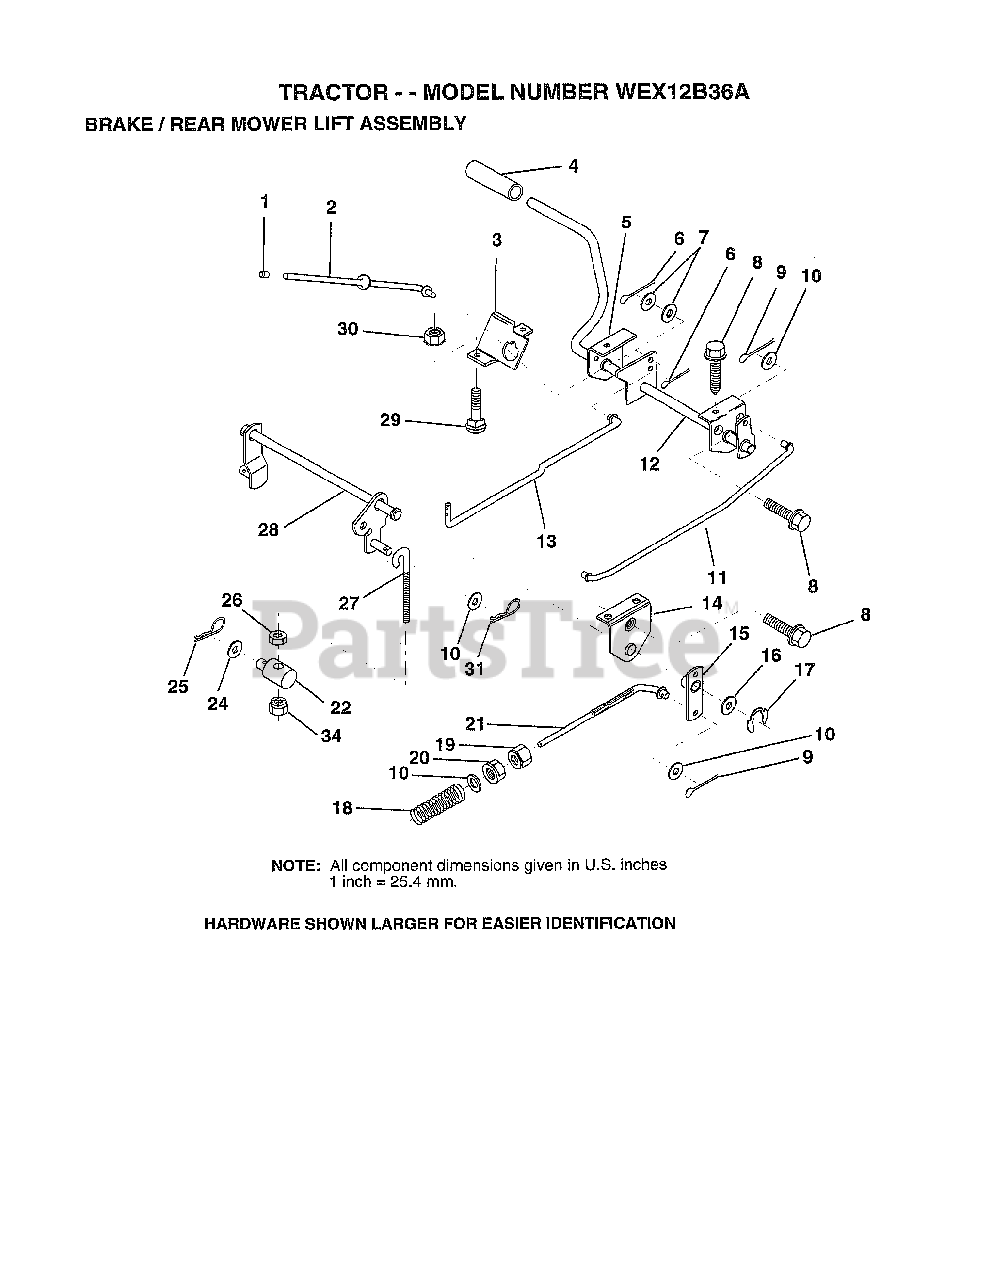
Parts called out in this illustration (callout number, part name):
1	PLUNGER CAP T
2	"ROD,PARK BRAKE"
3	"BRKT,PARK BRAKE"
4	FOOT PEDAL COVER
5	"BRKT,CLU PEDAL LH"
7	WASHER
8	SCREW LT
9	COTTER PIN
10	WASHER
11	"ROD,FRT BRAKE"
12	PEDAL ASM CL/BK36
13	"ROD,CLUTCH"
14	"BRKT,LIFT SHAFT"
15	PVT BRAKE ARM ASM
16	WASHER T
17	KLIP RING
18	SPRING ROD BRAKE
19	NUT
20	NUT
22	TRUNNION.LIFT.
24	WASHER
26	LOCKNUT
27	"LINK, MOWER REAR"
28	LIFT ASM MOW REAR
31	RETAINER.SPRING
